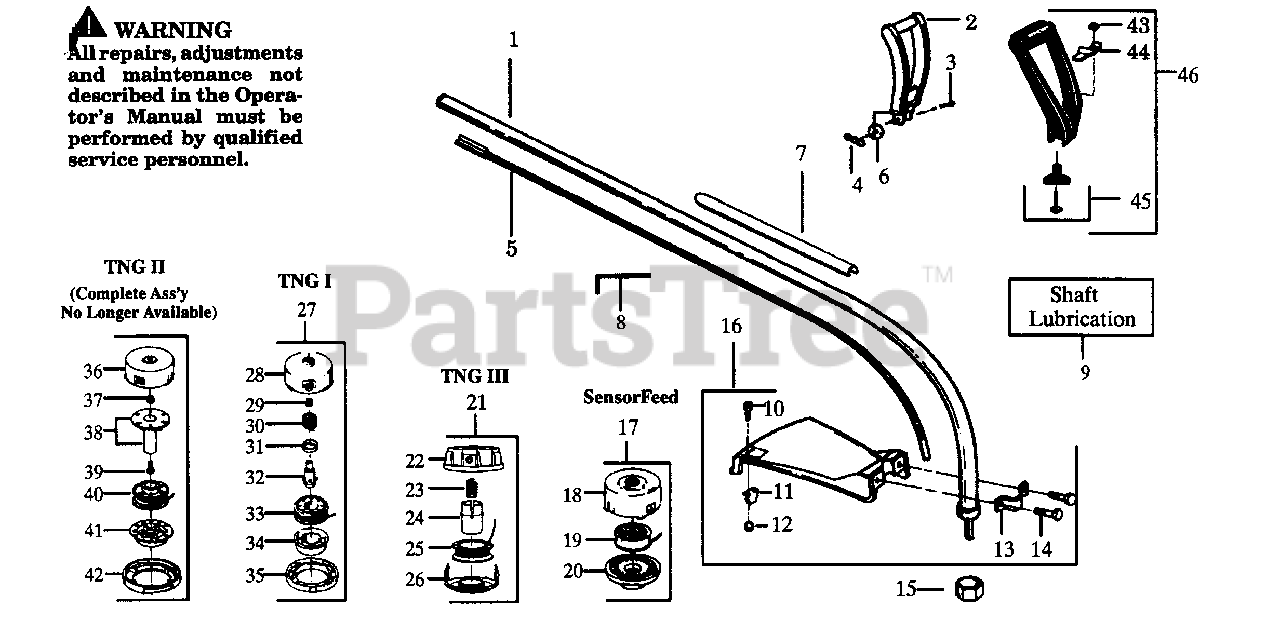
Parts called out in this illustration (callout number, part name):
1	MODEL GTI 17
1	MODELS GTI 17XP &GTI 17T Type 2
1	MODEL GTI 17C
1	MODEL GTI 17T Type 3
2	Handle- MODELS GTI 17, GTI 17XP & GTI 17C
4	Wing Nut
5	MODELS GTI 17 & GTI 17C
5	MODELS GTI 17XP, GTI 17T
7	MODELS GTI 17,GTI 17T(Type 2),GTI 17C,GTI 17XP
7	MODEL GTI 17T Type 3
8	Hex Wrench (5/32)
9	Shaft Lubrication
11	MODELS GTI 17 & GTI 17C
11	MODELS GTI 17XP,GTI 17T
12	Nut
13	MODELS GTI 17, GTI 17T & GTI 17XP
13	MODEL GTI 17C
15	Dust Cup
16	MODELS GTI 17,GTI 17T & GTI 17XP
16	MODEL GTI 17C
17	Cutting Head Ass'y -
18	Hub Ass'y MODEL GTI
19	Spool w/Line MODEL GTI
20	Cover MODEL GTI
21	Cutting Head Ass'y -
22	Hub Ass'y MODEL GTI 17C
23	Spring MODEL GTI 17C
24	Release Button MODEL GTI 17C
25	Spool w/Line MODEL GTI 17C
26	Cover MODEL GTI 17C
27	Cutting Head Ass'y -
28	Hub w/Line Saver MODELS GTI 17 & GTI 17T
29	Line Saver MODELS GTI 17 & GTI 17T
30	Spring MODELS GTI 17 & GTI 17T
31	Spring Adapter MODELS GTI 17 & GTI 17T
32	Drive Gear MODELS GTI 17 & GTI 17T
33	Spool w/Line MODELS GTI 17 & GTI 17T
34	Release Button MODELS GTI 17 & GTI 17T
35	Cover MODELS GTI 17 & GTI 17T
36	Hub Ass'y
38	Locking Plate Kit
40	Spool w/Line
41	Release Button
43	Nut, Square-Handle MODEL GTI 17T
44	Clamp- Handle MODEL GTI 17T
45	"T"-Handle Kit MODEL GTI 17T
46	Cushioned Handle Kit - (Inc.43,44,45) MODEL GTI 17T
